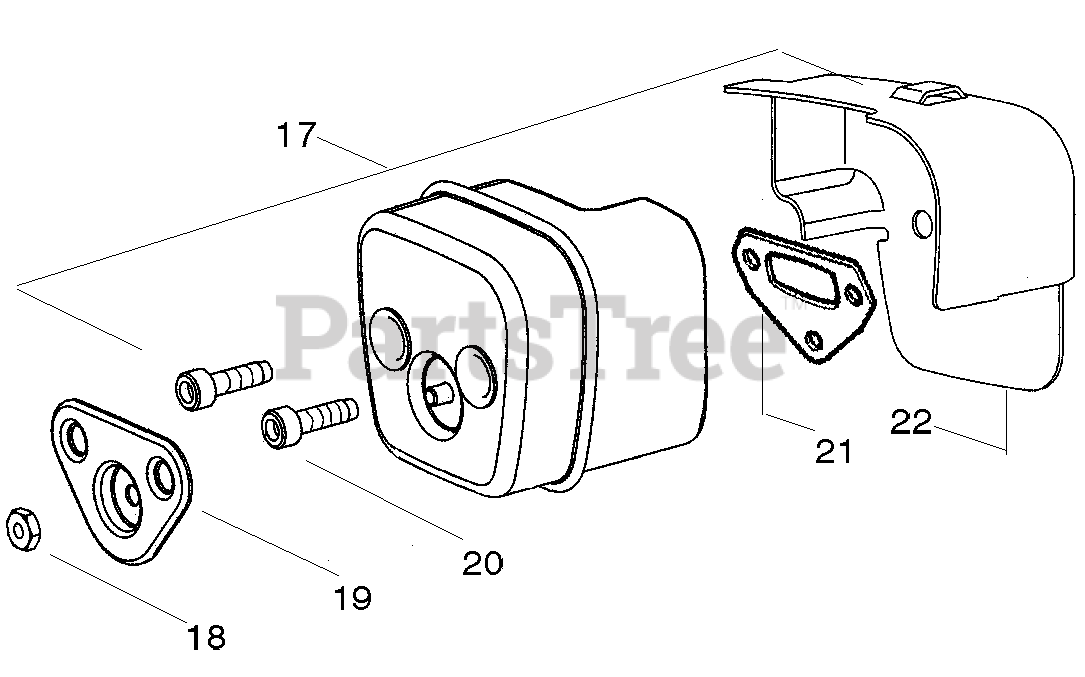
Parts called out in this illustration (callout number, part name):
17	Kit-Muffler
18	Nut-Brass
19	Cover-Bolt
20	Screw-Muffler
21	Gasket-Muffler
22	Backplate-Muffler
